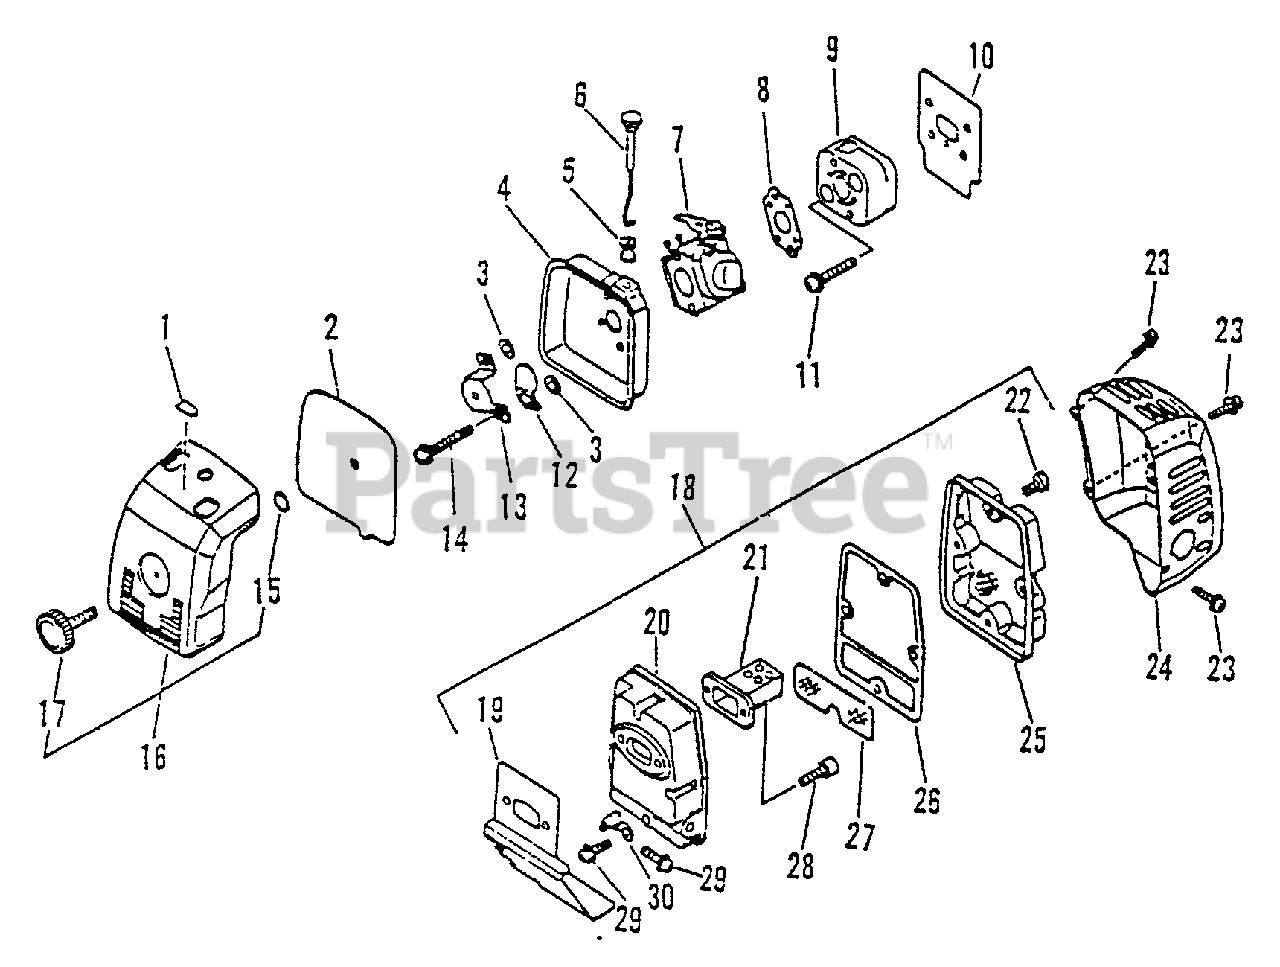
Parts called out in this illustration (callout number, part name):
1	LABEL, CHOKE
2	FILTER, HEAVY-DUTY AIR
3	WASHER 5.2×8×0.8T
4	CASE, AIR FILTER
5	GROMMET, CHOKE
6	ROD, CHOKE
7	CARBURETOR - C1U-K20
8	GASKET, INTAKE
9	INSULATOR
10	GASKET
11	SCREW 5×25
12	SHUTTER, CHOKE
13	PLATE, PREVENT
14	SCREW 5×50
15	O-RING 3
16	AIR FILTER COVER ASSY
17	THUMBSCREW
18	MUFFLER ASSY
19	GASKET, MUFFLER
21	SILENCER
22	BOLT 5×14
23	SCREW 4×8
24	COVER, MUFFLER
25	COVER, MUFFLER
26	GASKET, EXHAUST
27	SCREEN, SPARK ARRESTER
28	BOLT M5×18
29	SCREW 5×10
30	BRACKET, MUFFLER
